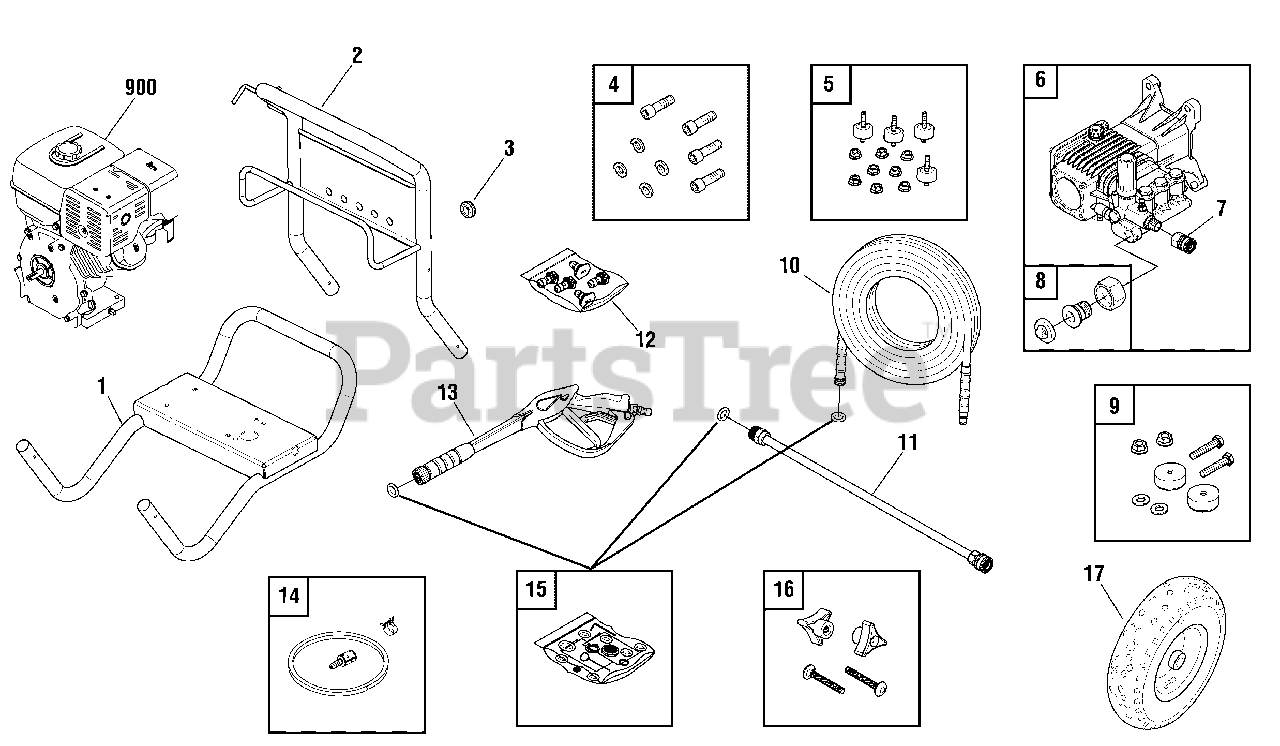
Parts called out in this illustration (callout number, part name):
4	KIT, Hardware, Engine Mounting
5	KIT, Hardware, Pump Mounting
6	PUMP
7	FITTING
8	ADAPTER, Garden Hose
9	MOUNT, Vibration
11	EXTENSION, QC
12	KIT, QC Nozzles
13	GUN
16	KIT, Hardware, Handle
900	* ENGINE
